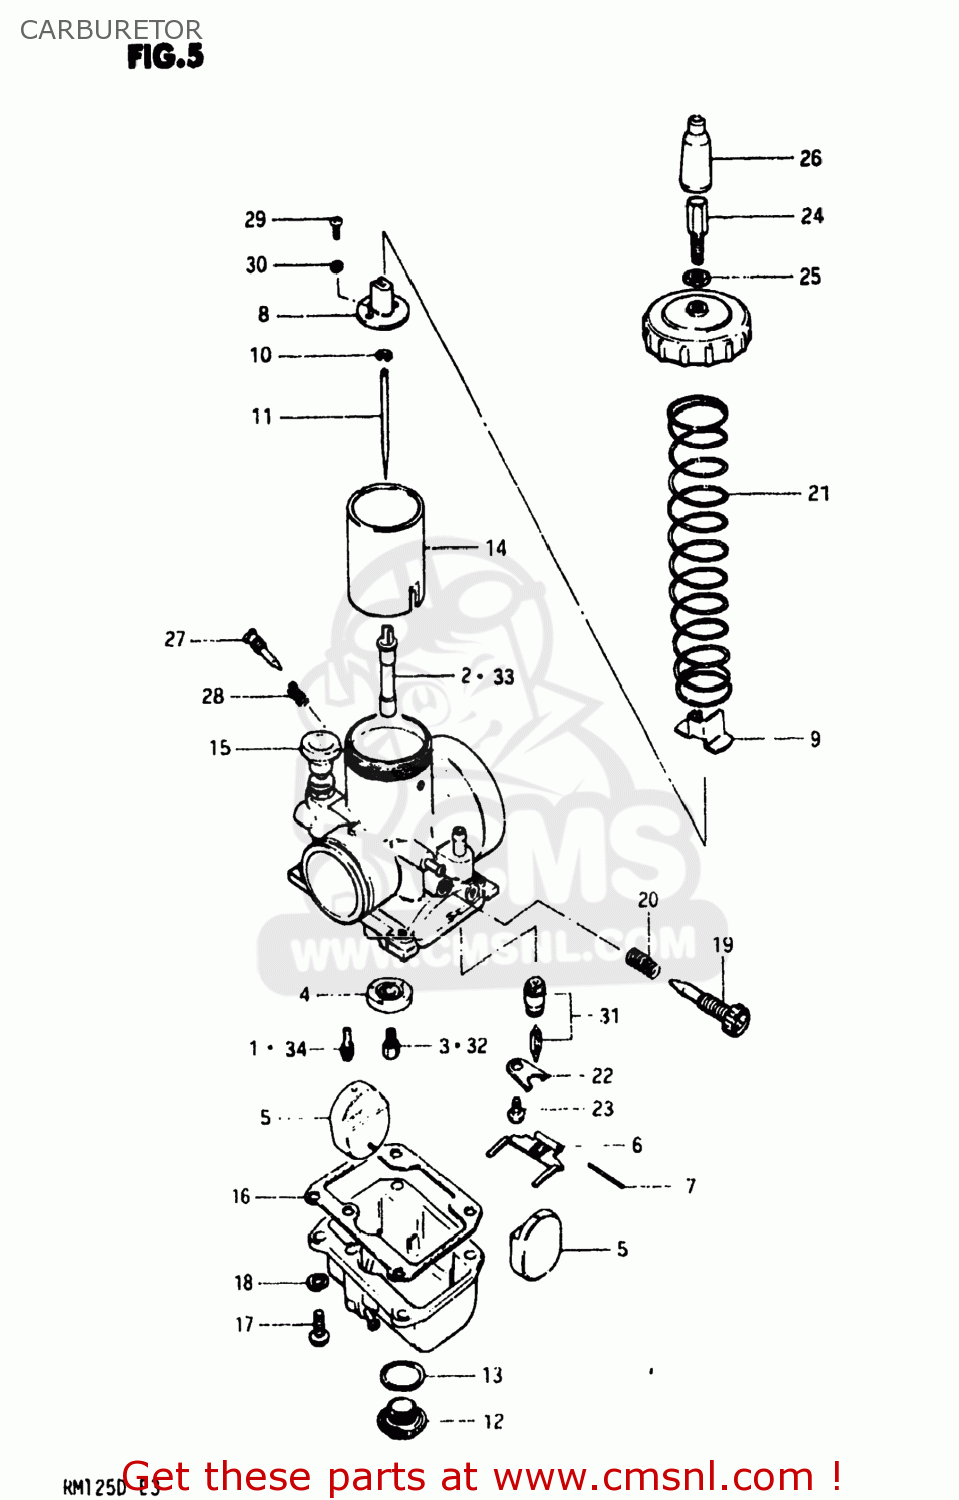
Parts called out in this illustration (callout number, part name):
1	JET
2	JET,NEEDLE
3	JET
4	RING,MAIN JET FIXING
5	FLOAT
6	ARM,FLOAT
7	PIN,FLOAT
8	CONNECTOR
9	COVER,HOLDER
10	CLIP
11	NEEDLE,JET
12	PLUG
13	O RING(D:1.5,ID:19.5)
14	VALVE,THROTTLE
15	VALVE ASSEMBLY,STARTER
16	GASKET,FLOAT CAHMBER (NAS)
17	SCREW
18	LOCK WASHER
19	SCREW,THROTTLE STOP
20	SPRING
21	SPRING,THROTTLE VALVE RETURN
22	PLATE
23	SCREW 4X6
24	ADJUSTER,CABLE
25	NUT
26	CAP,CABLE ADJUSTER
27	SCREW,PILOT AIR
28	SPRING
29	SCREW
30	LOCK WASHER
31	VALVE ASSY,NEEDLE
32	JET
33	JET,NEEDLE
34	JET
